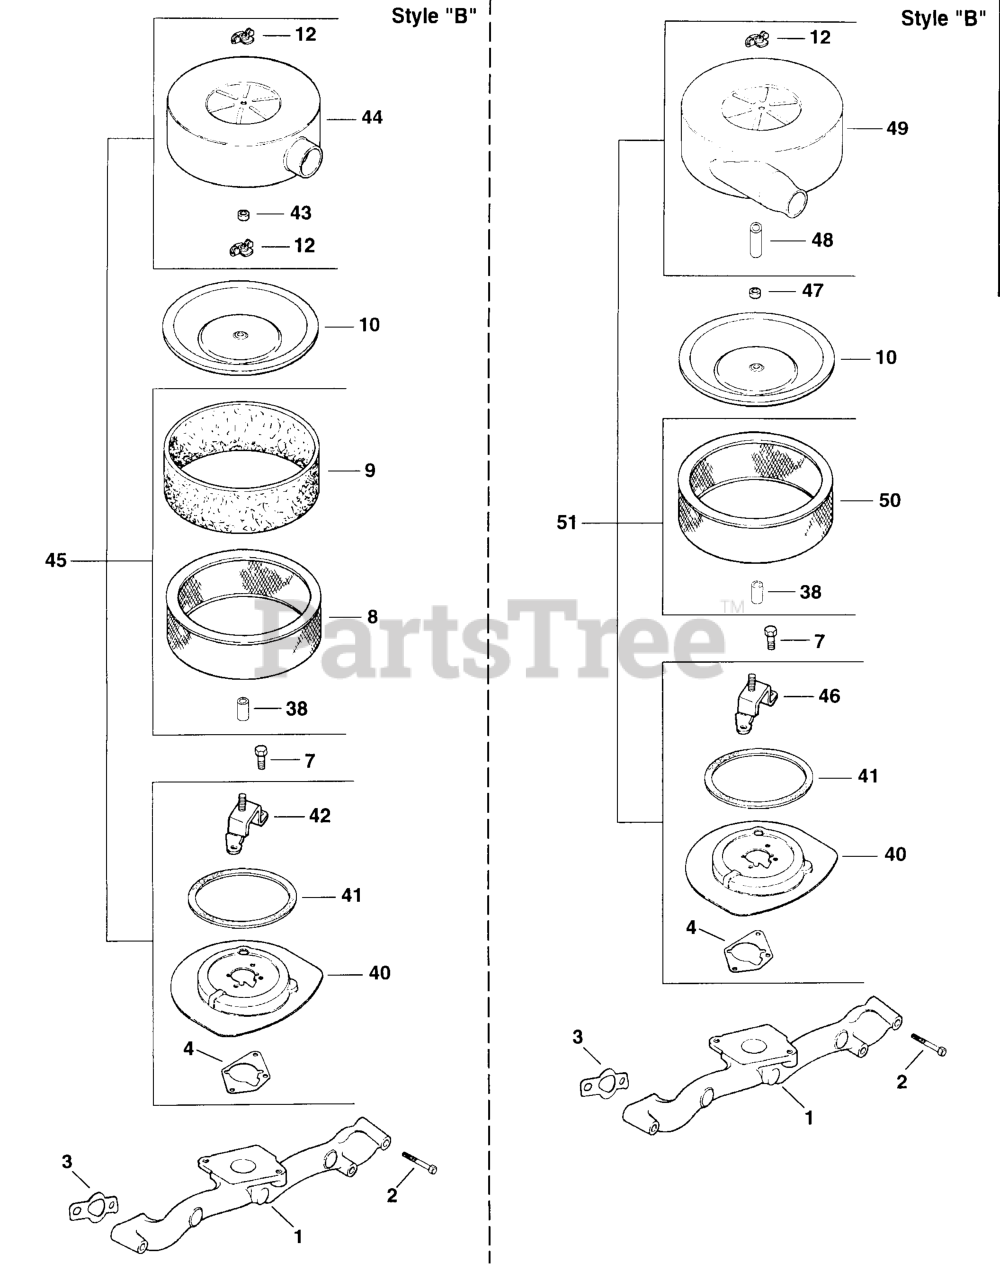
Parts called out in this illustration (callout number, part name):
1	MANIFOLD, METAL INTAKE
2	Screw, hex. flange M6x1.0x55
3	GASKET, INTAKE MANIFOLD USE 24 041 79-S
4	GASKET, AIR CLEANER BASE
7	SCREW - USE M-645016
8	ELEMENT, AIR FILTER (HIGH) - Also available Retail Packaged 24 883 03-S1 Air Filter Kit
9	PRE-CLEANER (HIGH)
10	COVER, INNER AIR CLEANER
12	NUT, WING
38	SEAL, BREATHER
